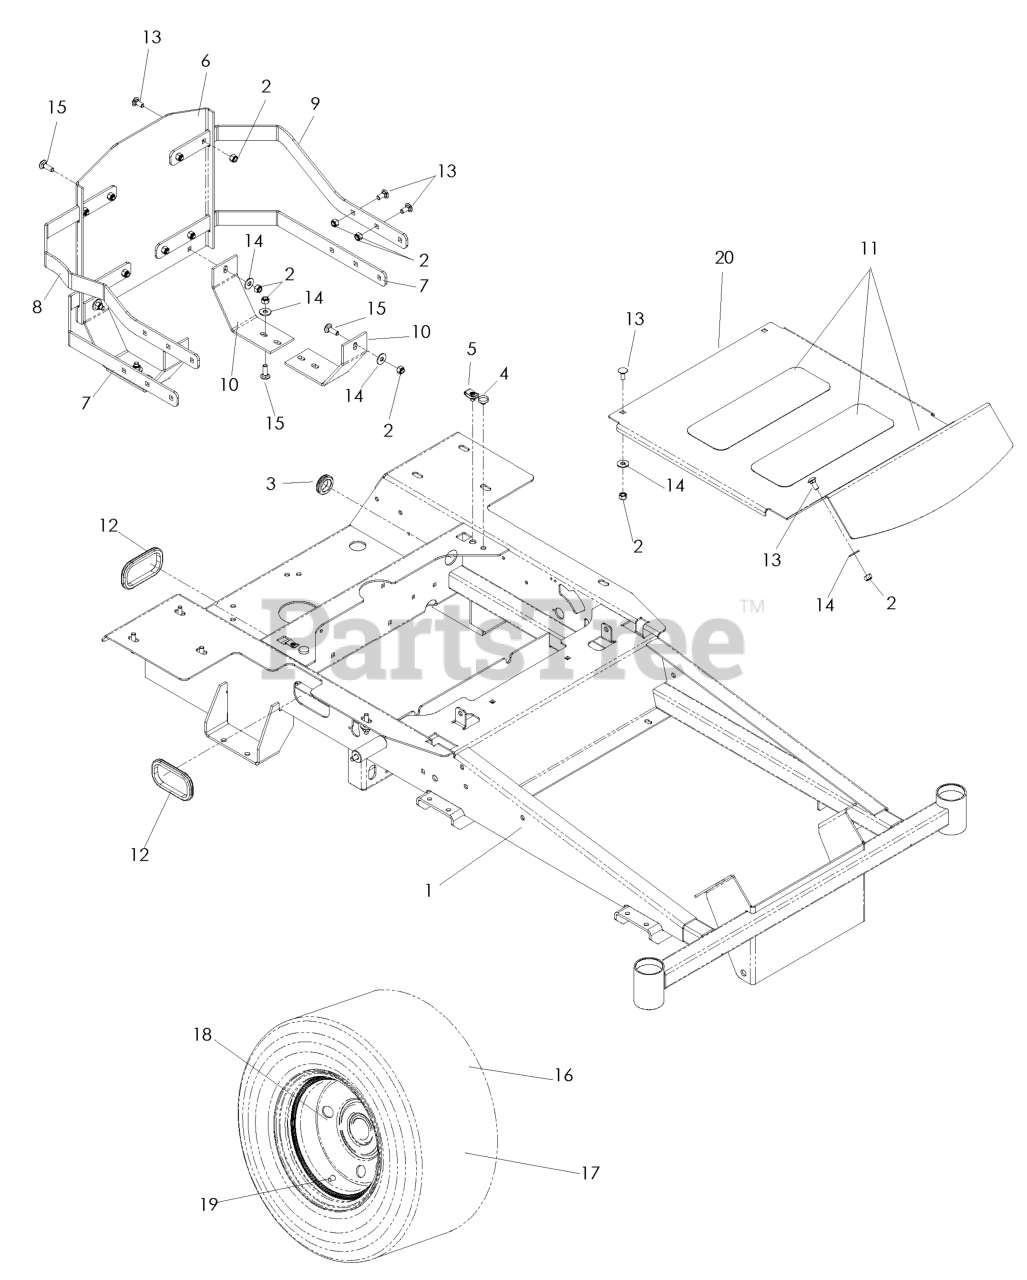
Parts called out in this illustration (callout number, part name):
1	FRAME W/DECALS
2	NUT 5/16 NYLOC
3	RUBBER GROMMET
4	GROMMET, BUMPER
5	U-CLIP 5/16-18 NUT RETAINER
6	ENGINE GUARD
7	REAR GUARD STRAP, LOWER
8	REAR GUARD STRAP, UPPER RIGHT
9	REAR GUARD STRAP, UPPER LEFT
10	SKID PLATE
11	ANTI-SKID PAD
13	BOLT 5/16C X 3/4" CARRIAGE
14	WASHER 5/16 FLAT
15	RHSNB 5/16C X 1
16	TIRE/WHEEL ASM 18X9.5-8
17	TIRE, 18 X 9.5 - 8
18	RIM.8X7.W/8".OFFSET.SILVER.ZTR
19	VALVE STEM TR-412
